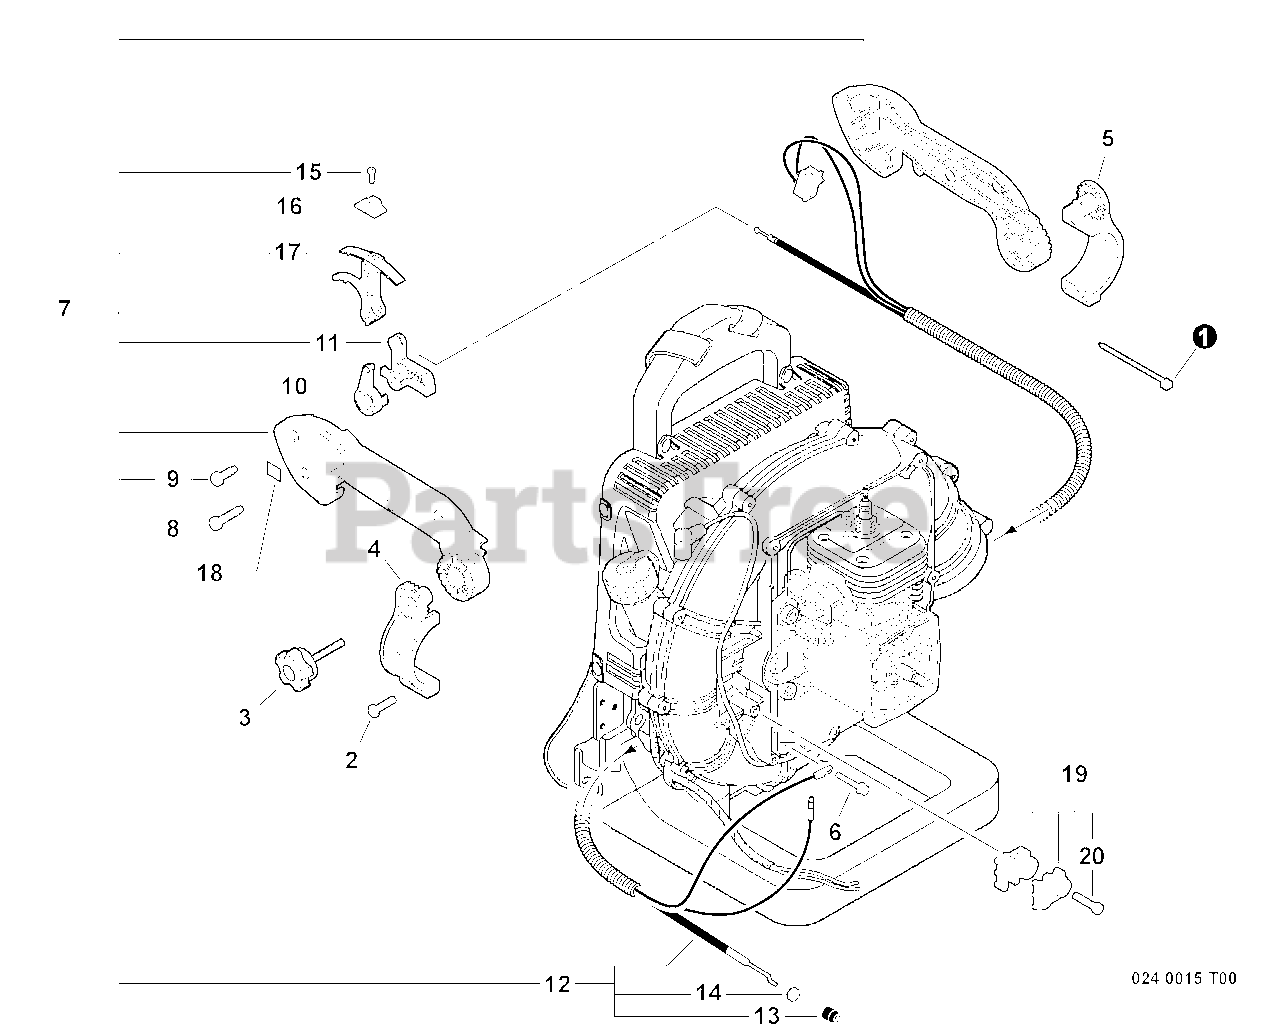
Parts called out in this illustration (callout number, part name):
1	TIE, CABLE - SMALL
2	SCREW - 5X20 -- TAPPING
3	THUMBSCREW
4	BRACKET, HANDLE - LEFT
5	BRACKET, HANDLE - RIGHT
6	SCREW - 5
7	CONTROL HANDLE ASSY
8	SCREW - 5X32
9	SCREW - 5X20
10	LEVER, THROTTLE
11	TRIGGER, THROTTLE
12	CONTROL CABLE ASSY
13	CAP, DUST
14	LOCKNUT - 6
15	SCREW - 3X14
16	KNOB, THROTTLE CONTROL
17	LEVER, THROTTLE CONTROL
18	LABEL - IDLE
19	CABLE BRACKET KIT
20	SCREW - 5X25 -- TAPPING
